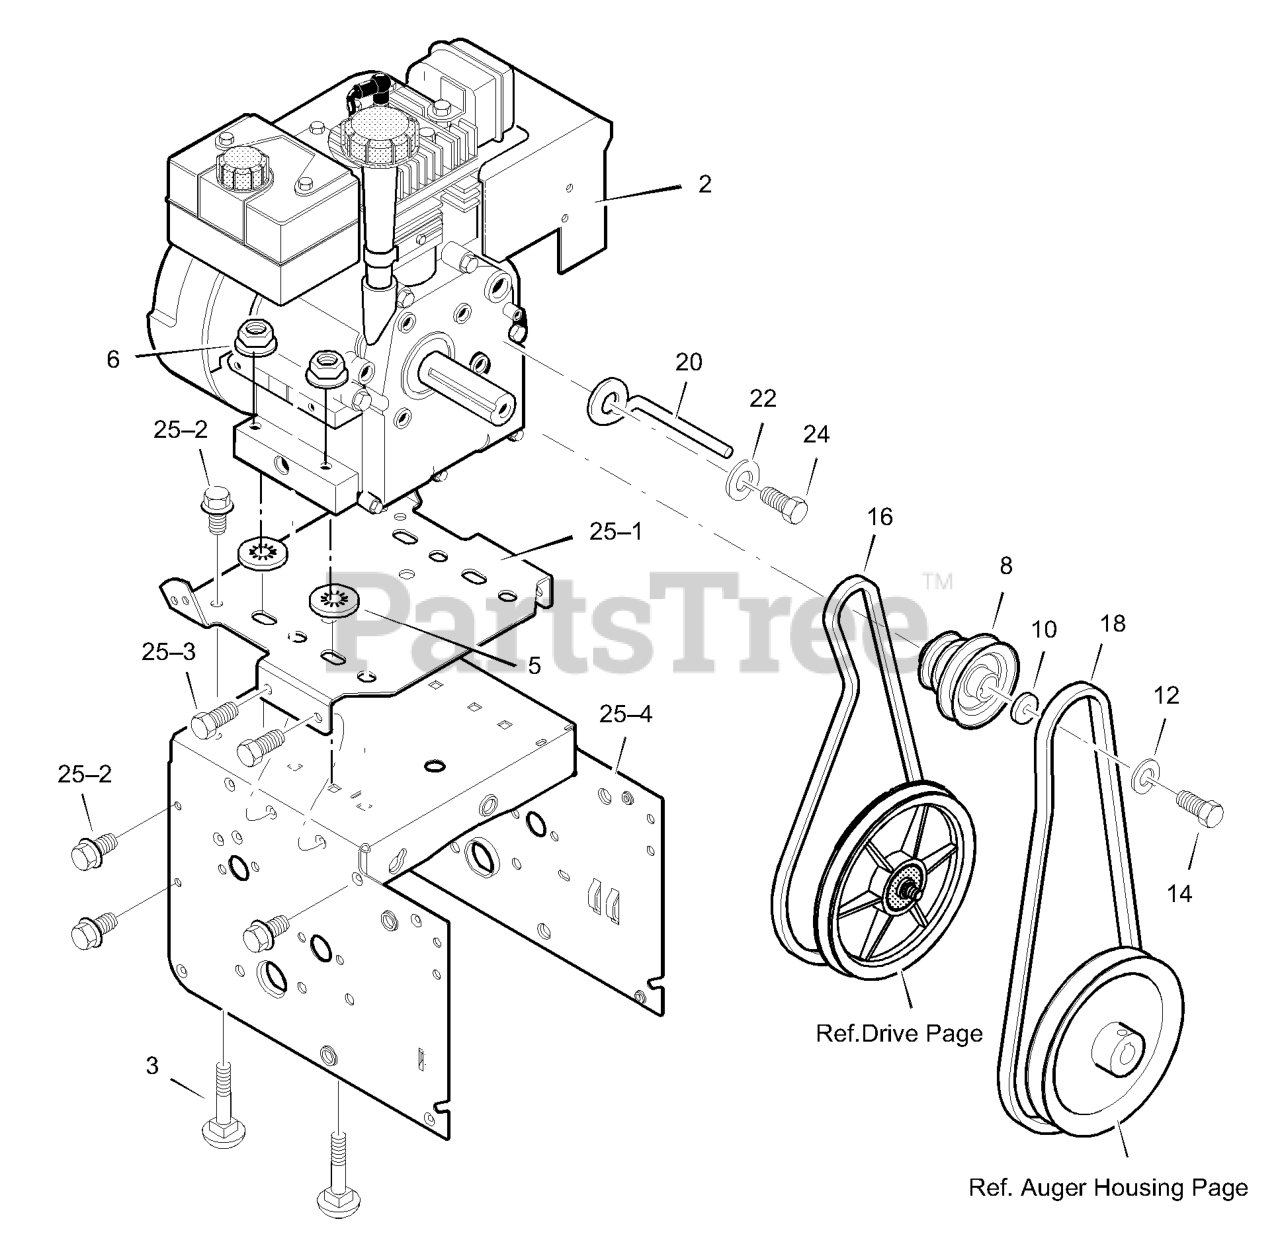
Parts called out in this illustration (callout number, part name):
2	ENGINE
3	BOLT, CARRIAGE 5/16-18
5	RETAINER, PUSH
6	NUT, HEXWDFLLK 5/16-18
8	PULLEY, ENGINE
10	WASHER
12	WASHER,HVSPTLK .38ID
14	SCREW, 3/8-24 x 1.00
16	BELT, V 3L 33.79 LG
18	BELT, V 4L 39.2 MF16"
20	GUIDE, BELT
22	WASHER, SPTLK .31X.58X.08
24	SCREW, 5/16-24 x 0.75
25	FRAME ASSEMBLY
25-1	PLATE, ENGINE MOUNT
25-2	SCREW, TAP 1/4-20 X .63
25-3	SCREW, TAP 5/16-18 X .50
25-4	FRAME, MOTOR BOX
